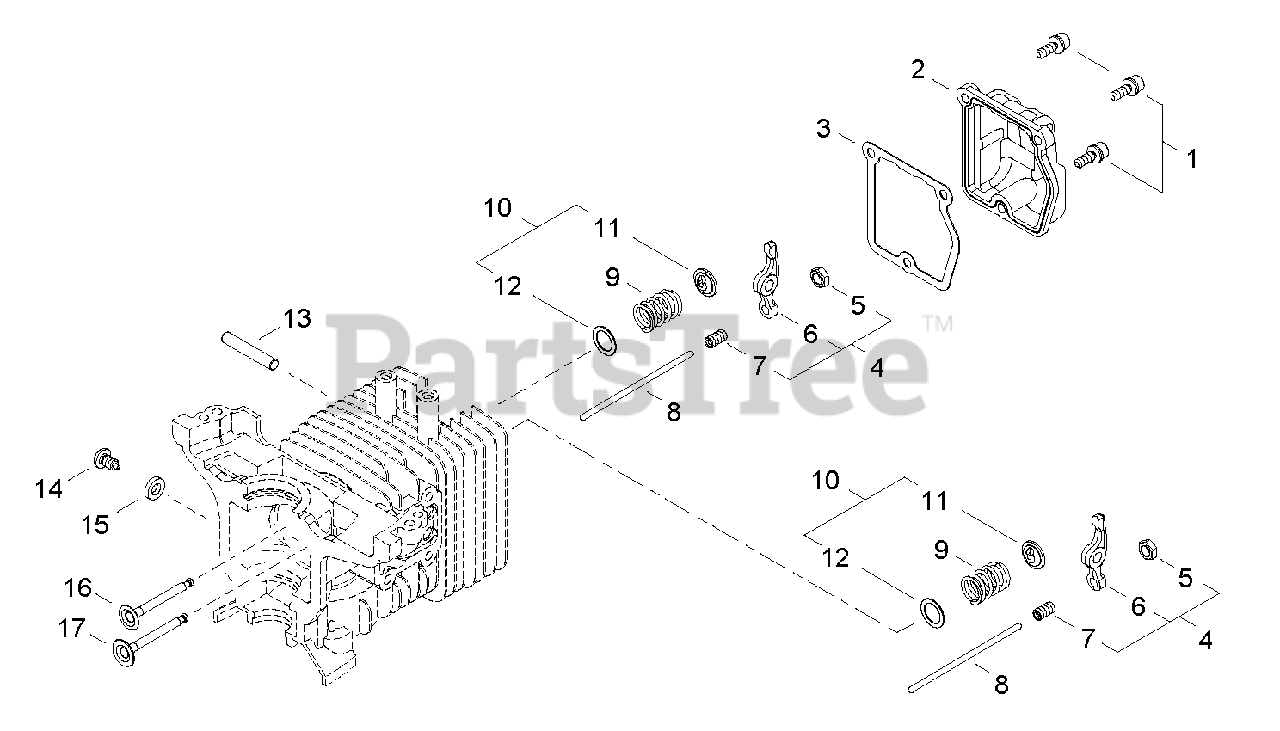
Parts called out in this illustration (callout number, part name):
1	SCREW - 4X14
2	COVER, ROCKER ARM
3	GASKET
4	ROCKER ARM ASSY
5	LOCKNUT, ADJUSTER
6	ARM, ROCKER
7	SCREW, ADJUST
8	PUSHROD
9	SPRING, VALVE
10	VALVE RETAINER ASSY
11	RETAINER, VALVE
12	WASHER, VALVE 9
13	SHAFT, ROCKER ARM - 5X31.8
14	SCREW - 5
15	WASHER
16	VALVE, EXHAUST
17	VALVE, INTAKE
